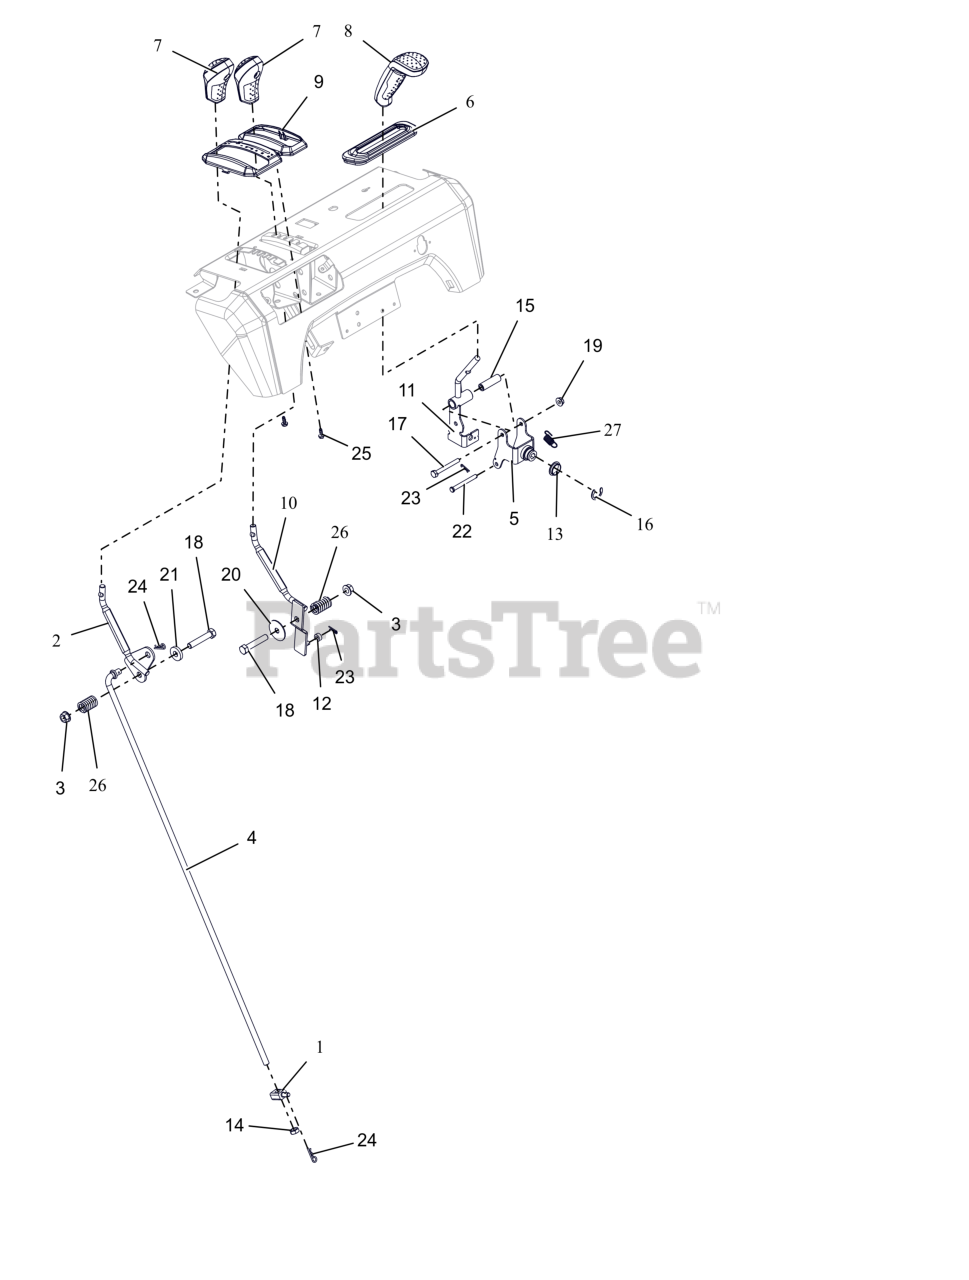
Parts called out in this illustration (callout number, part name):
1	PIVOT,SHIFT ROD .375-16(TRUNN)
2	WELDMENT,LG DASH SPEED CONTROL
3	NUT-LK-TOP-FLG .38-16 ZC120
4	ROD, SHIFT - LARGE DASH DELUXE
5	WELDMENT, CONTROL BRACKET
6	GROMMET, BOOT, QUICK TURN
7	KNOB, CONTROL, DASH
8	HANDLE, QUICK TURN, ASM
9	BEZEL, SHIFT - FRICTION SNOW
10	WELDMENT,LG DASH DEFL CONTROL
11	WELDMENT, CONTROL LEVER
12	BSHG-SLV .265X.500X.219
13	BUSHING, POLYLINER-.75 SNAPIN
14	NUT-JAM .375-16 G2 ZCC
15	BSHG, SLV .265X.505X1.665
16	E-RING .750X.050
17	BLT,HEX .25-20X2.25 G5 ZCC
18	BLT,HEX .38-16X2.00 G5 ZCC
19	NUT-LK-CTR-FLG .25-20 ZC120
20	WSHR,FLT .380X1.50X.062 ZCC
21	WSHR, FLT .406X1.00X.188 ZCC
22	PIN, CLEVIS - .25 X 2.25 ZCC
23	PIN, HAIR #178 .06X.77 ZCC
24	PIN, HAIR #213 .08X1.19 ZCC
25	SCR, PLASTIC #10X.50
26	SG-COMP .125X.781X1.250
27	SPRING-EXT .047X.438X1.45
